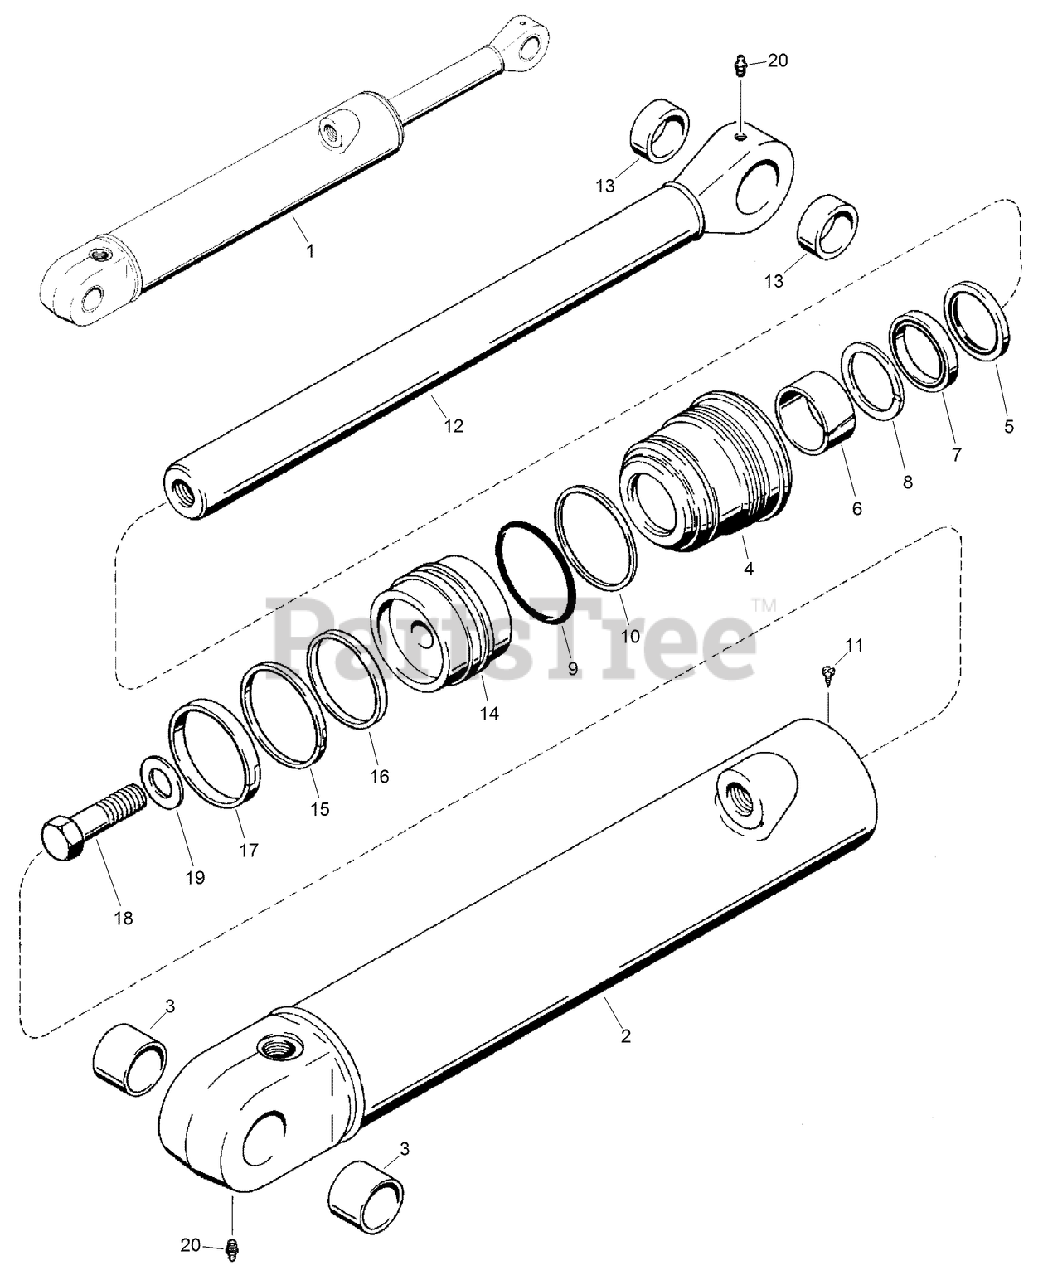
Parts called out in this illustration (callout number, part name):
1	CYLINDER-76 (3) ID x 498 mm (19-5/8 inch) Stroke, Dipper
2	TUBE ASM-Cylinder
3	BUSHING-Cylinder Tube
4	Gland-Cylinder
5	WIPER-ROD
6	BEARING-ROD
7	SEAL-U-Cup, Piston Rod, Wide, with O-Ring
7	SEAL-U-Cup, Piston Rod, service option-severe heat or cold
8	SEAL-Piston Rod, Narrow, Grooved
9	O-RING
10	RING-BACKUP
12	ROD ASM-Piston, 38 mm (1-1/2 inch) diameter
13	BUSHING
14	PISTON-Cylinder
15	SEAL-Piston
16	RING-LOADER
17	RING-WEAR
18	BOLT-Hex, 1 NF x 2-1/2 inch, grade 8
19	WASHER-Flat, Special, Hardened
20	FITTING-Lube 1/8-27 Dryseal PTF
